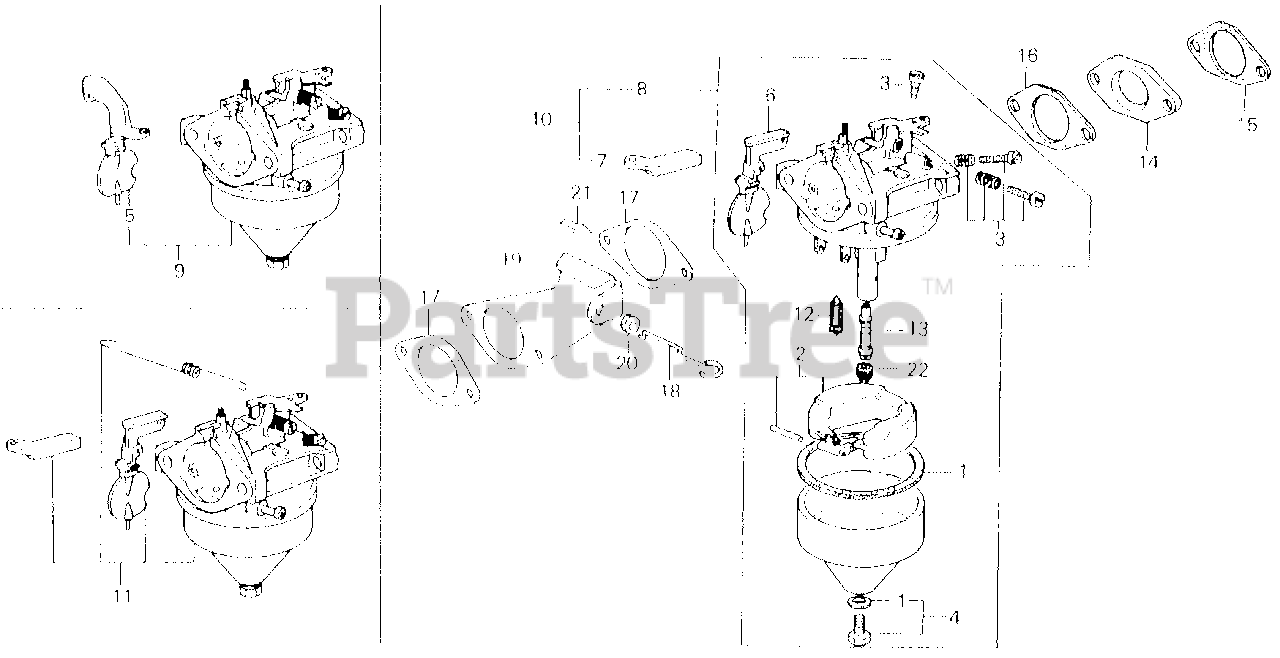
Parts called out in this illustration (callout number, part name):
1	GASKET SET
2	FLOAT SET
3	SCREW SET A
4	SCREW SET B
5	CHOKE SET (NOT AVAILABLE)
6	CHOKE SET
7	ARM, CHOKE LEVER
8	CARBURETOR ASSY.
8	CARBURETOR ASSY. (BB30A D)
9	CARBURETOR ASSY.
9	CARBURETOR ASSY. (BB30A A)
10	CARBURETOR ASSY.
11	CARBURETOR ASSY.
12	VALVE, FLOAT
13	NOZZLE, MAIN
14	INSULATOR, CARBURETOR
15	GASKET, INSULATOR
16	GASKET, CARBURETOR
17	GASKET, AIR CLEANER
18	ROD, CHOKE CONTROL
19	STAY, CHOKE CONTROL
20	GROMMET, CHOKE ROD
21	MARK, CHOKE
22	JET, MAIN (#65) Use up to Engine SN BB30A D.
22	JET, MAIN (#68) Use up to Engine SN BB30A D.
22	JET, MAIN (#70) Use up to Engine SN BB30A D.
22	JET, MAIN (#72)
